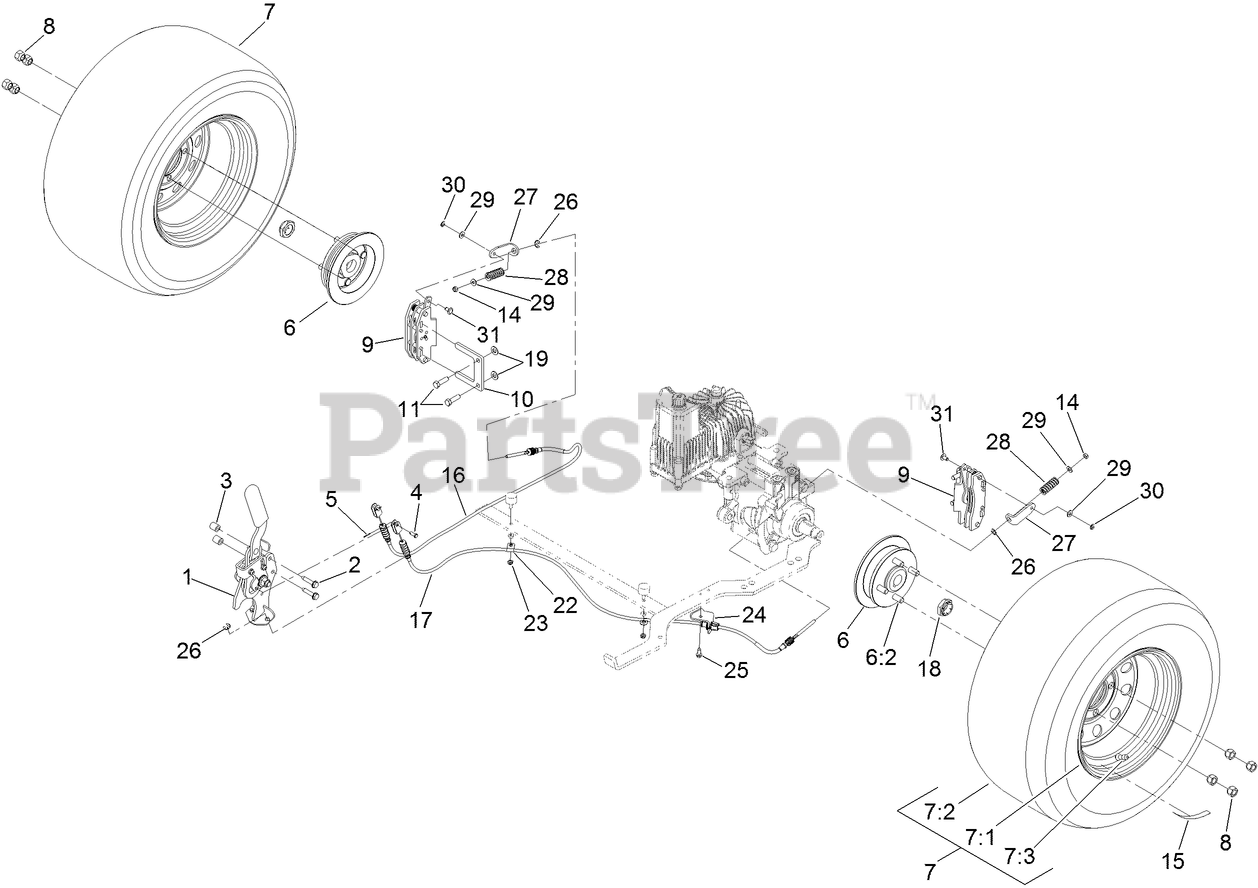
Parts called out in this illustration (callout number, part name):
1	BRAKE HANDLE ASM
3	SPACER
4	PIN-CLEVIS
5	PIN-COTTER
6	WHEEL HUB ASM
6:2	STUD-WHEEL
7	TIRE AND WHEEL ASM
7:2	TIRE-TURF MASTER
7:3	STEM-VALVE
8	NUT-LUG
9	CALIPER-BRAKE
10	PLATE-MOUNT, BRAKE
11	SCREW-LOCK, PATCH
14	NUT-LOCK, NI
15	DECAL-WHEEL NUT TORQUE
16	CABLE-PARK BRAKE, RH
17	CABLE-PARK BRAKE, LH
18	LOCKNUT
19	WASHER-FLAT
23	NUT-LOCK, NI
24	BRACKET-CABLE
25	SCREW-HWH
26	E-RING
27	BRACKET-BRAKE, L
28	SPRING-DIE
29	WASHER-FLAT
30	E-RING
31	PIN-BRAKE
